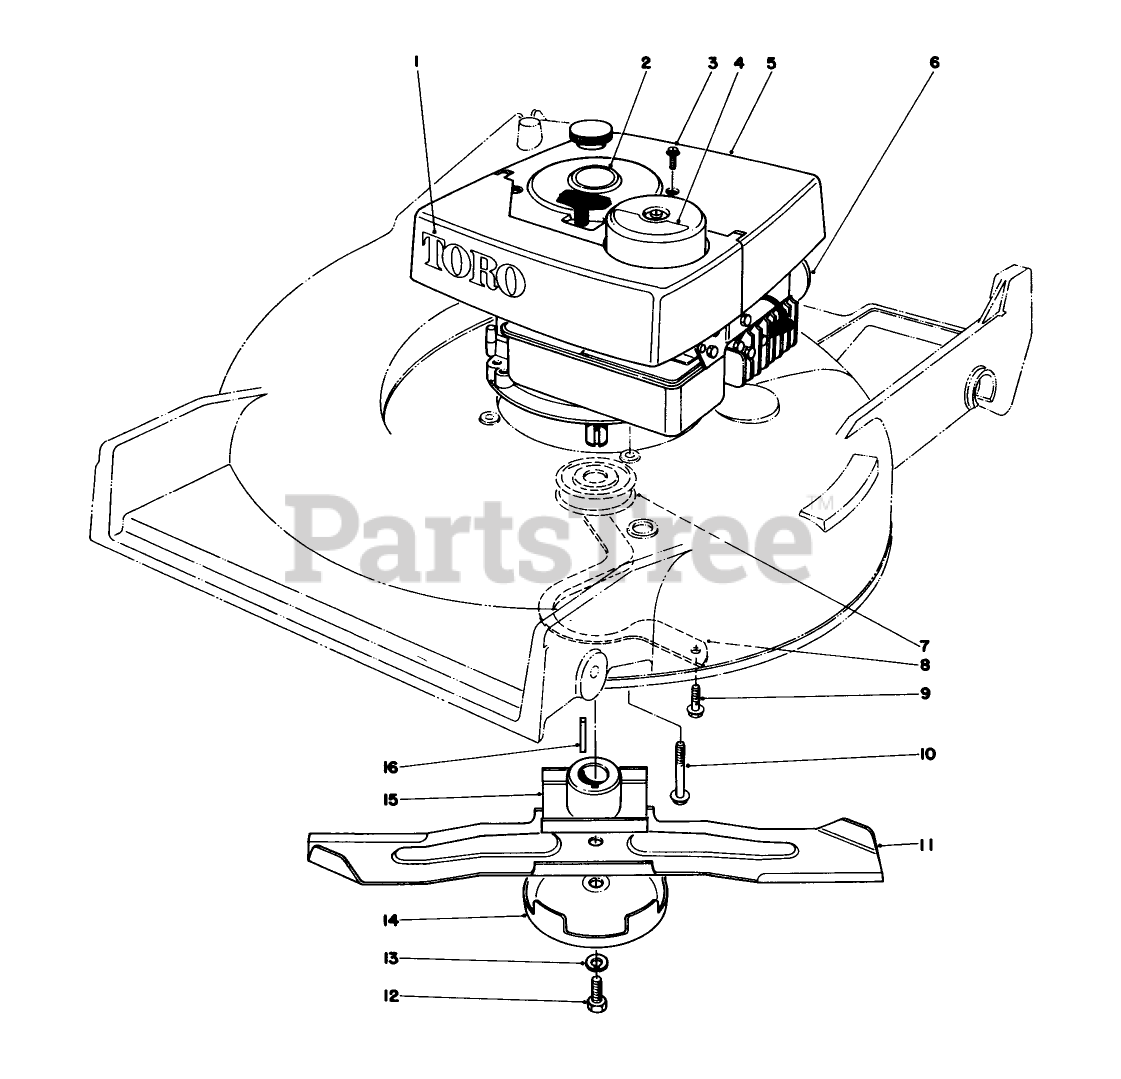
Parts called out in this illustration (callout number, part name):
4	Decal-Air Filter (French Dutch)
6	Engine
12	SCREW-BLADE
13	WASHER-LOCK
16	KEY-SQUARE
